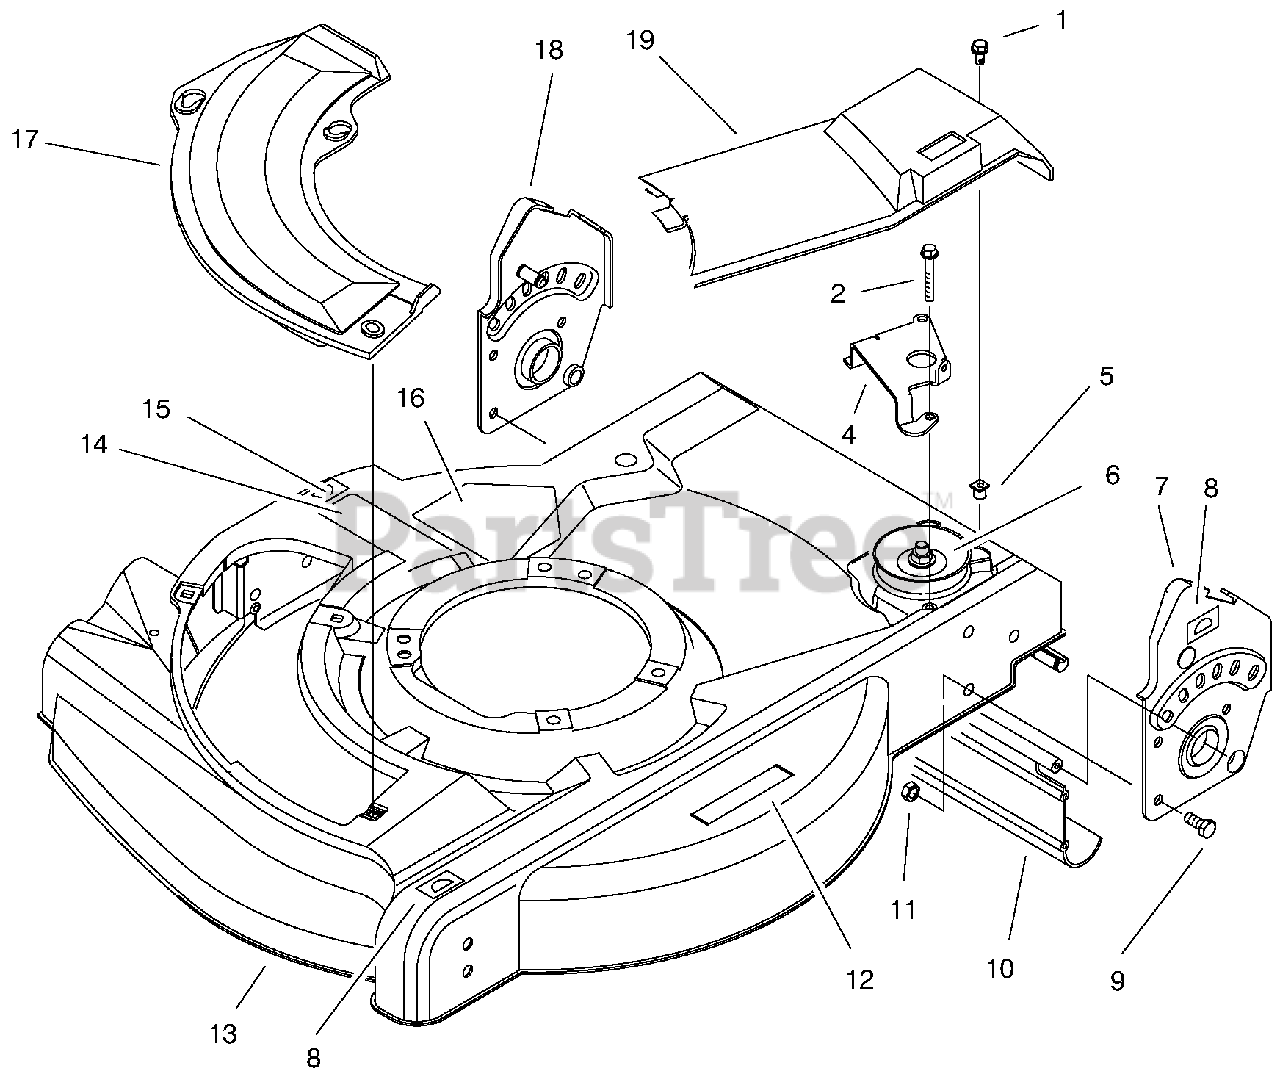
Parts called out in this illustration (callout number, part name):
1	Screw-Phillips Hd.
2	Screw-Hex Hd.
4	Guide-Transmission
5	Grommet
6	Gear Case Assembly
7	Bracket-Handle L.H.
8	Decal-H.O.C.
9	Screw-Hex Hd. Cap
10	Shield-Trailing
11	Nut-Lock
12	Decal-Warning
13	Housing
14	Decal-Discharge
15	Decal-H.O.C.
16	Decal-Danger
17	Plate-Cover
18	Bracket-Handle R.H.
19	Cover-Drive
